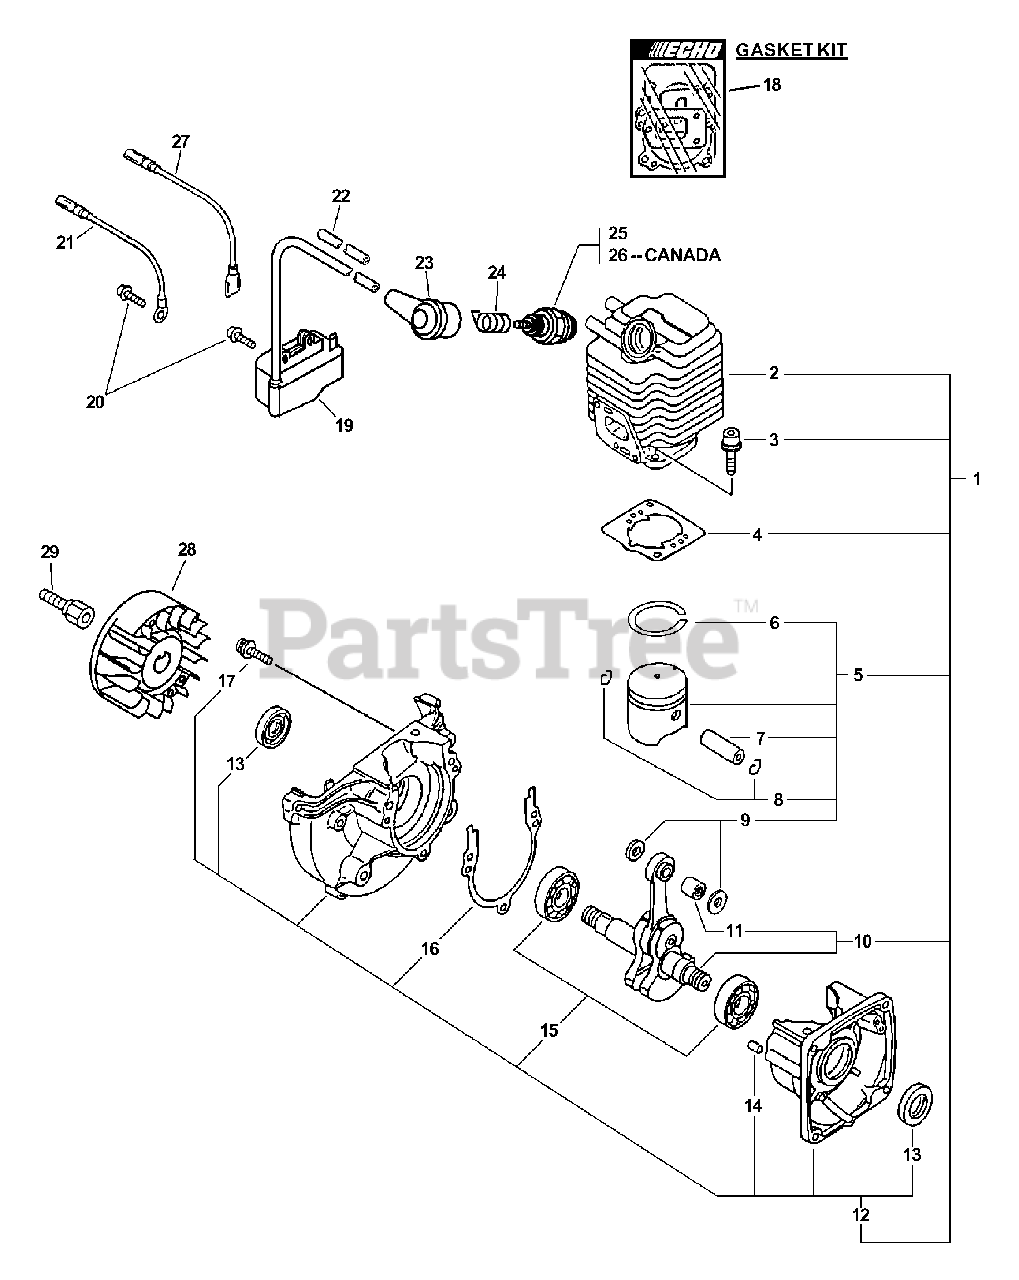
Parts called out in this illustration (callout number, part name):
1	SHORT BLOCK -- SB1076
2	CYLINDER
3	SCREW - 5X22
4	GASKET, CYLINDER
5	PISTON KIT
6	RING, PISTON
7	PIN, PISTON
8	RING, RETAINING
9	SPACER, PISTON
10	CRANKSHAFT ASSY
11	BEARING, NEEDLE
12	CRANKCASE KIT
13	SEAL, OIL
14	PIN - LOCATING
15	BEARING, BALL - 6201
16	GASKET, CRANKCASE
17	SCREW - 5X28
18	GASKET KIT
19	COIL, IGNITION
20	SCREW - 4X20
21	LEAD - GROUND
22	TUBE, INSULATOR
23	CAP, SPARK PLUG
24	TERMINAL, SPARK PLUG CAP
25	SPARK PLUG -- BPM-8Y
26	SPARK PLUG -- BPMR-8Y
27	LEAD - IGNITION
28	FLYWHEEL
29	HUB, FAN
